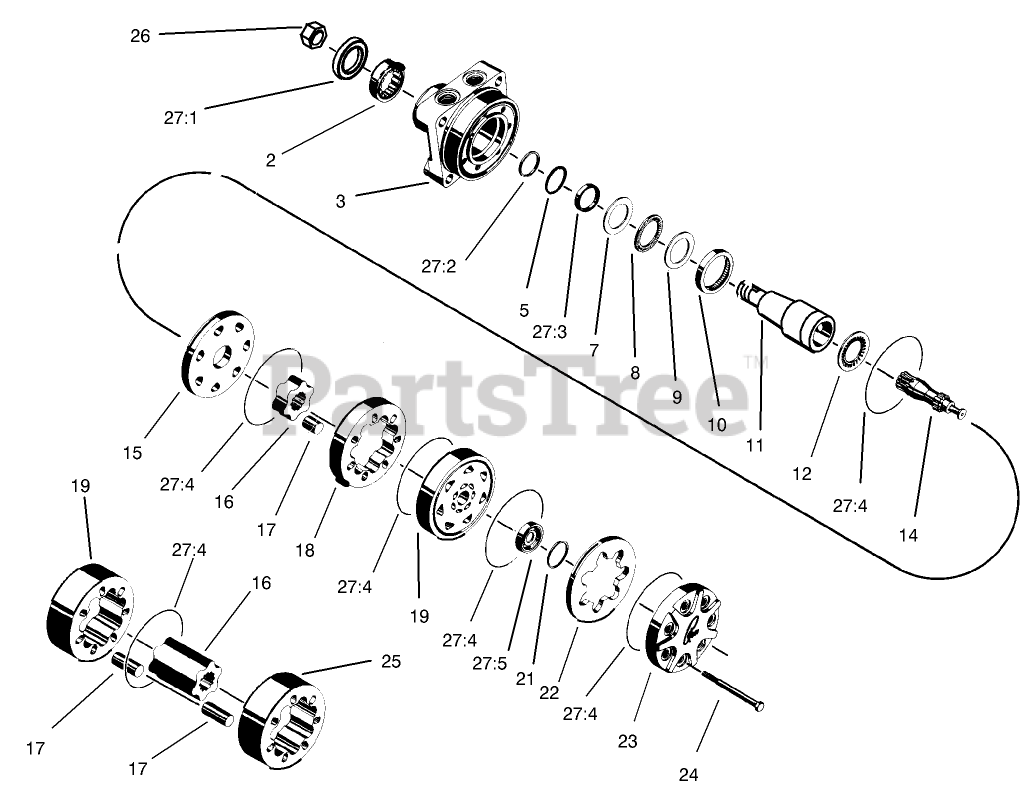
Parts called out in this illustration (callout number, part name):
2	Bearing
3	Housing
5	Washer-Back Up
7	Washer-Thrust
8	Bearing-Thrust
9	Washer-Thrust
10	Bearing-Inner
11	Coupling-Shaft
12	Bearing-Thrust
14	Link-Drive
15	Plate-Wear
16	Rotor
17	Vane
18	Stator
19	Manifold
21	Seal-Commutator
22	Commutator-Ring
23	Cover-End
24	Bolt-Special
25	Stator-Half
26	NUT-MOTOR, WHEEL
27:1	Seal ASM
27:2	Washer-Back Up
27:3	Seal ASM
27:4	Seal-Dust
27:5	Commutator
